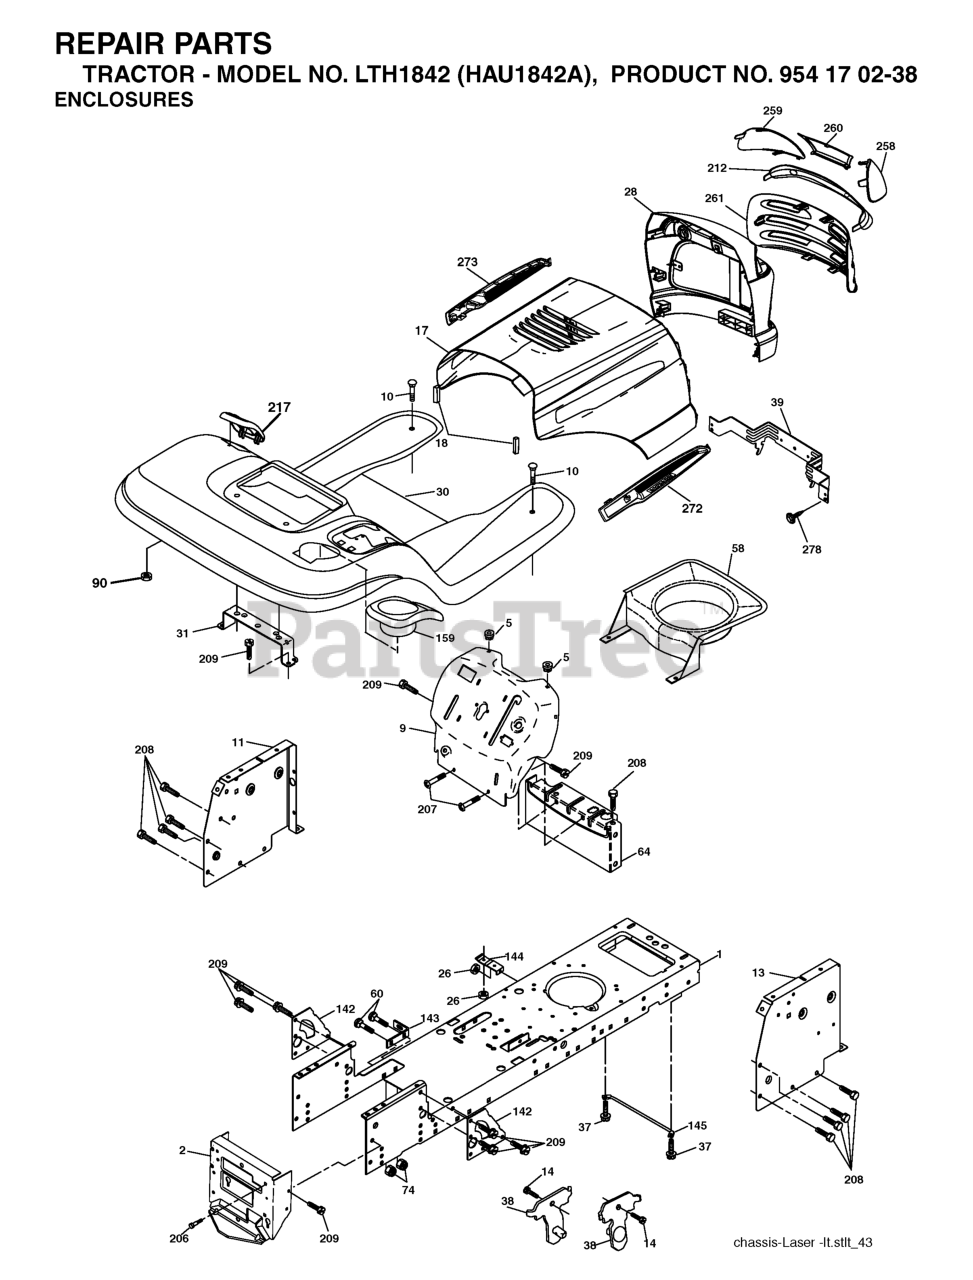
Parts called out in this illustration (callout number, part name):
1	CHASSIS STAMPING
2	DRAWBAR, 12GA
5	BUMPER.RUBBER.HOOD
10	BOLT D
11	PANEL.DASH.LH.LTX
13	PANEL DASH RH
17	VENT.HOOD.LASER.III
18	BUMPER.HOOD.LARGE.1.75"
26	NUT
30	FENDER STL W/CUPHOLDER
31	BRACKET.SUPPORT.FENDER
37	Screw 5/16-18 x 1/2 Hex, Self Tapping 5/16-18 x 1/2
38	BRACKET.ASM.PIVOT.MOWER.REAR
39	BRACKET PIVOT LASER
60	Bolt - Rd. Hd. Sq. Neckiage 3/8 16 x 3/4
64	DASH LOWER
90	NUT.PUSH.3/16
142	PLATE REINFORCEMENT
143	BRACKET, SWAYBAR CHASSIS
144	BRKT, FOOT REST
145	ROD PIVOT CHASSIS/HOOD
159	CUPHOLDER
206	SHOULDER BOLT 5/16-18TT
207	SCREW, 5/16-18 X 1/2
208	SCREW 3/8-16X1/2
209	SCREW, 3/8-16X3/4
212	INSERT.LENS.REFLECTIVE
217	CONSOLE FUEL WINDOW
258	LENS LH
259	LENS LH
260	COVER.LENS.HUSQ.( HAVE GRAY)
261	INSERT GRILLE
272	VENT.HOOD.LASER.
273	VENT.HOOD.LASER.
278	SCREW
